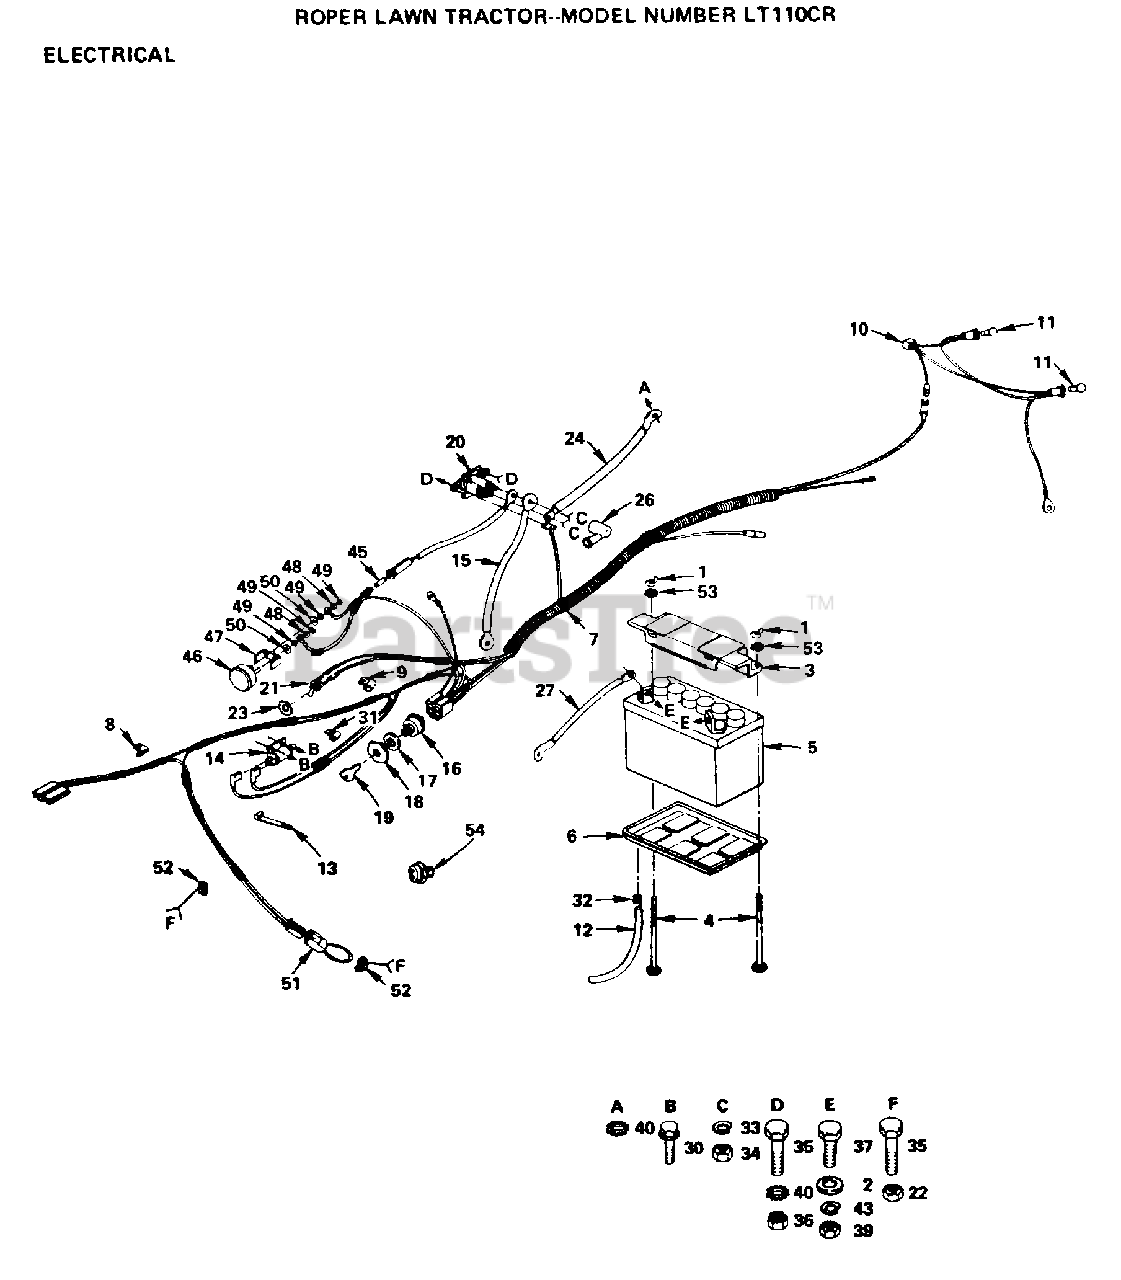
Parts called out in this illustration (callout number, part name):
2	WASHER
4	BOLT
6	"TRAY T, BATTERY"
8	CLIP GTV
10	HARNESS T
13	WIRE TIE
15	"CABLE T, BATTERY"
17	LOCKWASHER
18	CONDUIT NUT L
21	LIGHT SWITCH T
27	CABLE ASSY LT
31	CLIP T
34	NUT
35	BOLT
36	NUT
37	BOLT LT
43	LOCKWASHER
45	FUSE-30 AMP
46	AMMETER T
52	CLIPT
53	LOCKWASHER GT
54	"SWITCH, INTERLO T"
